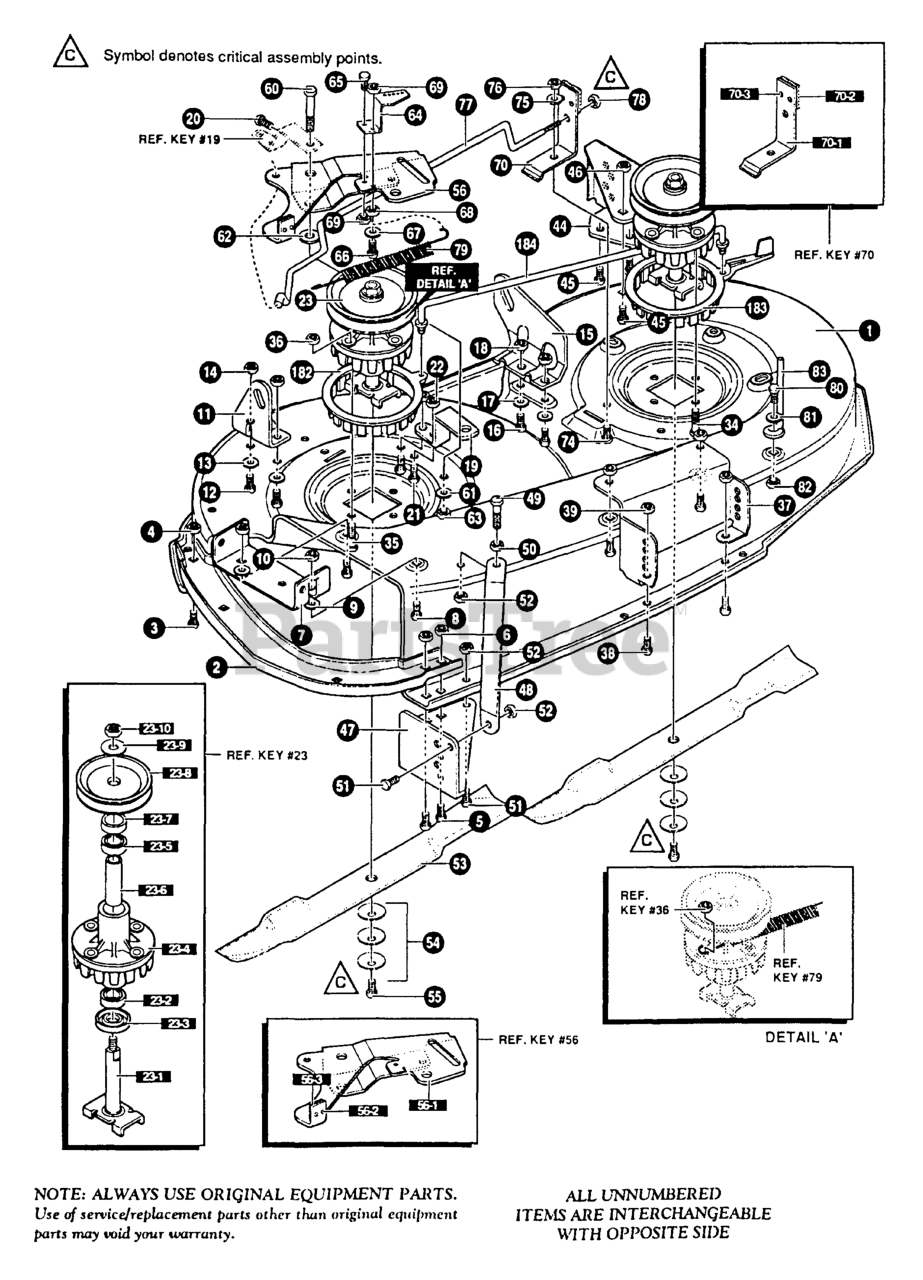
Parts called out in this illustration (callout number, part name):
1	43" DECK KIT
2	TOE GUARD
3	SCREW, 5/16-18 x 0.75
4	NUT, 5/16-18
5	SCREW, 5/16-18 x 0.75
6	NUT, 5/16-18
7	BRACKET, CHUTE MOUNT
8	SCREW, 5/16-18 x 0.75
9	WASHER, FLAT .344 X .69 X .065
10	NUT, 5/16-18
11	BRACKET, RH LIFT REAR
12	SCREW, 5/16-18 x 0.75
13	WASHER, FLAT .344 X .69 X .065
14	NUT, 5/16-18
15	BRACKET, LH LIFT REAR
16	SCREW, 5/16-18 x 0.75
17	WASHER, FLAT .344 X .69 X .065
18	NUT, 5/16-18
19	BRACE, IDLER SUPPORT
20	SCREW, 1/4-20 X 1.25
21	SCREW, 5/16-18 x 0.75
22	NUT, 5/16-18
23	QUILL ASSEMBLY
23-1	SHAFT/SADDLE
23-2	BEARING, BALL
23-3	DUST SHIELD
23-5	BEARING, BALL
23-6	SPACER, SLEEVE
23-7	SPACER, QUILL
23-8	PULLEY
23-9	WASHER, SPECIAL QUILL
23-10	NUT, 7/16-20
34	SCREW, 5/16-18 x 2.00
35	SCREW, 5/16-18 x 2.25
36	NUT, 5/16-18
37	BRACKET FRONT
38	SCREW, 5/16-18 x 0.75
39	NUT, 5/16-18
44	BRACKET, GAGE WHEEL, LH
45	SCREW, 5/16-18 x 0.75
46	NUT, 5/16-18
47	BRACKET, GAGE WHEEL, RH FRONT
48	BRACKET, STABILIZER
49	SCREW, 5/16-18 X 5.00
50	NUT, 5/16-18
51	SCREW, 5/16-18 x 0.75
52	NUT, 5/16-18
53	BLADE, 21.70
54	WASHER, .39ID X 1.25D X .07
55	SCREW, 3/8-24 X 1.25
56	IDLER ARM ASSEMBLY
56-1	ARM IDLER
56-2	RIVET, OVSET
56-3	BRAKE PAD - HARD
60	BOLT, .500 X 2.15
61	WASHER, FLAT .391 X 1.00 X .125
62	WASHER, FLAT .391 X 1.00 X .209
63	NUT, 3/8-16
64	BRACKET, EXTENSION IDLER
65	SCREW, 5/16-18 x 0.75
66	SCREW, 5/16-18 x 1.50
67	WASHER, FLAT .375 X .88 X .082
68	NUT, 5/16-18
69	NUT, 5/16-18
70	BLADE BRAKE ASSEMBLY
70-1	RIVET, TRSET
70-2	BRAKE ARM
70-3	BRAKE PAD - HARD
74	SCREW, 5/16-18 x 0.75
75	WASHER, FLAT .344 X .69 X .065
76	NUT, 5/16-18
77	ROD, BRAKE
78	NUT, 1/4-20
79	SPRING
80	SCREW 5/16-18 X 1.00
81	WASHER, FLAT .344 X .69 X .065
82	NUT, 5/16-18
83	BELT GUIDE, UPSTOP
182	COVER-TURBO VENT
183	COVER-TURBO VENT W/HANDLE
184	LINK, TURBO VENT
